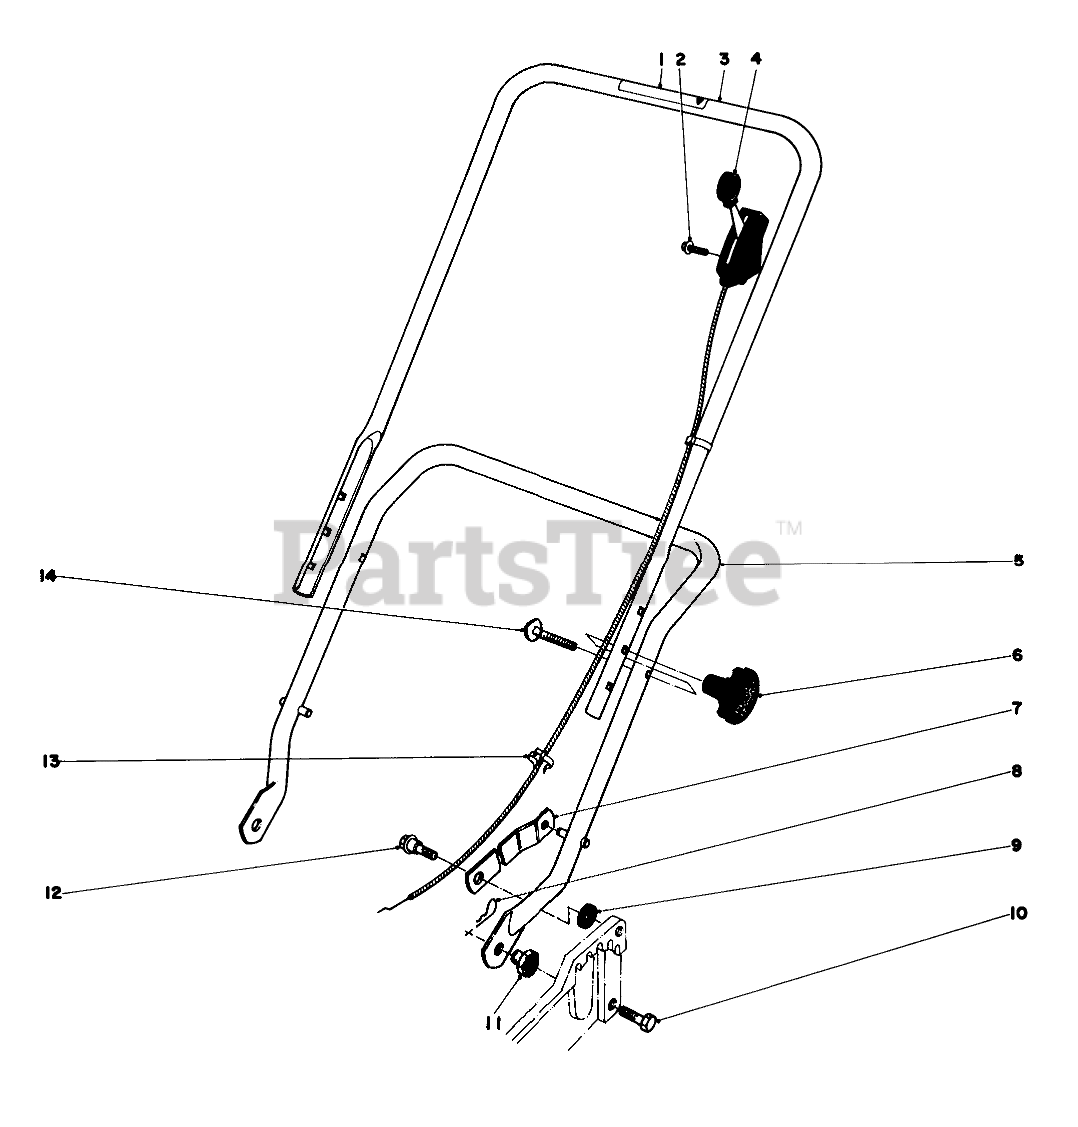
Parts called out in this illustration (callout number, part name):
1	Decal
3	Upper Handle (Incl. Ref. #1)
4	Throttle Control
5	LOWER HANDLE ASM
7	HANDLE LATCH
8	PIN-COTTER, HAIR
9	SPACER
10	SCREW-HH
11	HANDLE PIVOT NUT
12	SCREW-SHOULDER
13	BOWDEN CLIP
14	HANDLE SCREW
